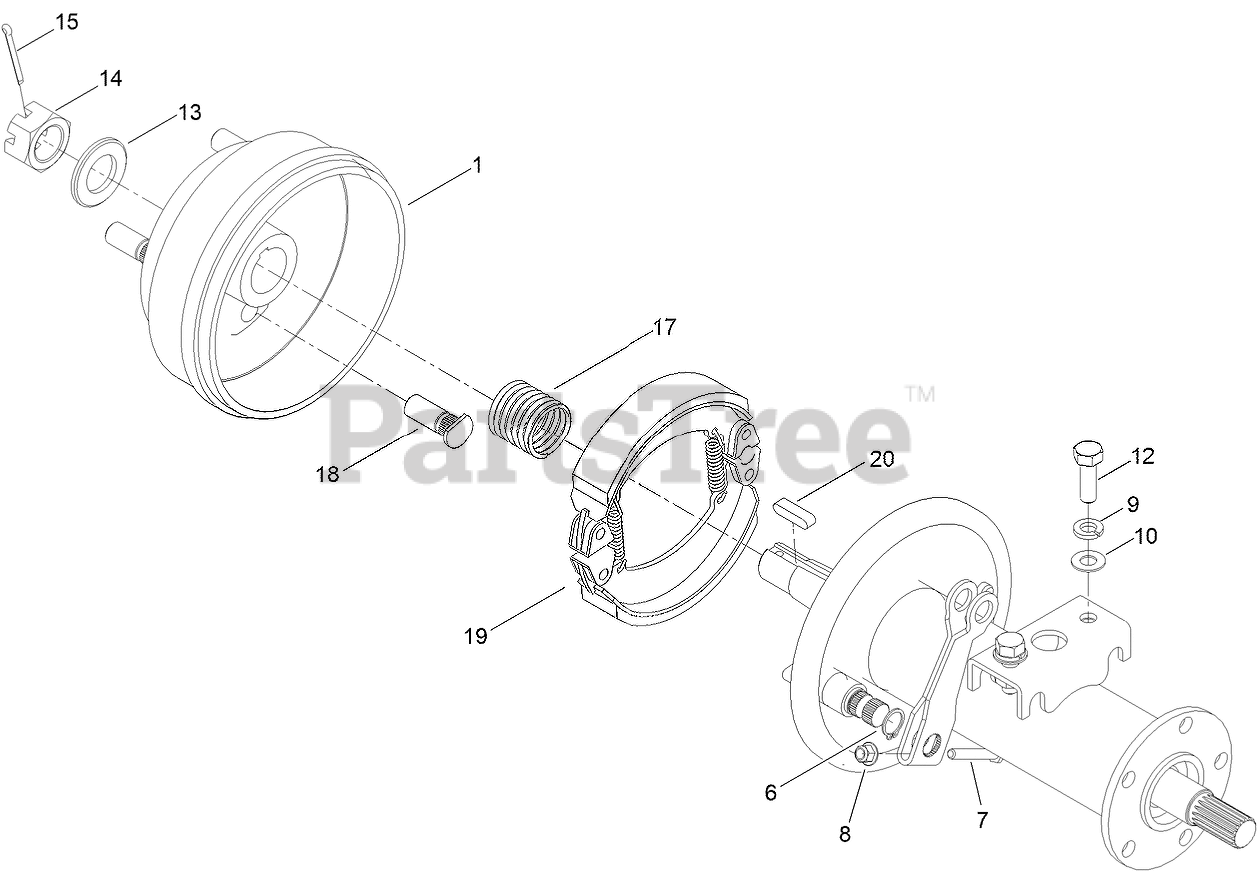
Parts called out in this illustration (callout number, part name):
1	REAR WHEEL MOUNTING PLATE ASM
6	CLIP, CONNECTION BRAKE
8	NUT-FLANGE, NI
9	SPRING WASHER
10	WASHER-PLAIN
12	SCREW-HH
13	WASHER, REAR WHEEL
14	CENTRE NUT, REAR WHEEL
15	PIN, WHEEL NUT
17	SPRING, REAR AXLE
18	BOLT, REAR AXLE
19	BRAKE PAD, REAR AXLE
20	KEY, REAR AXLE
